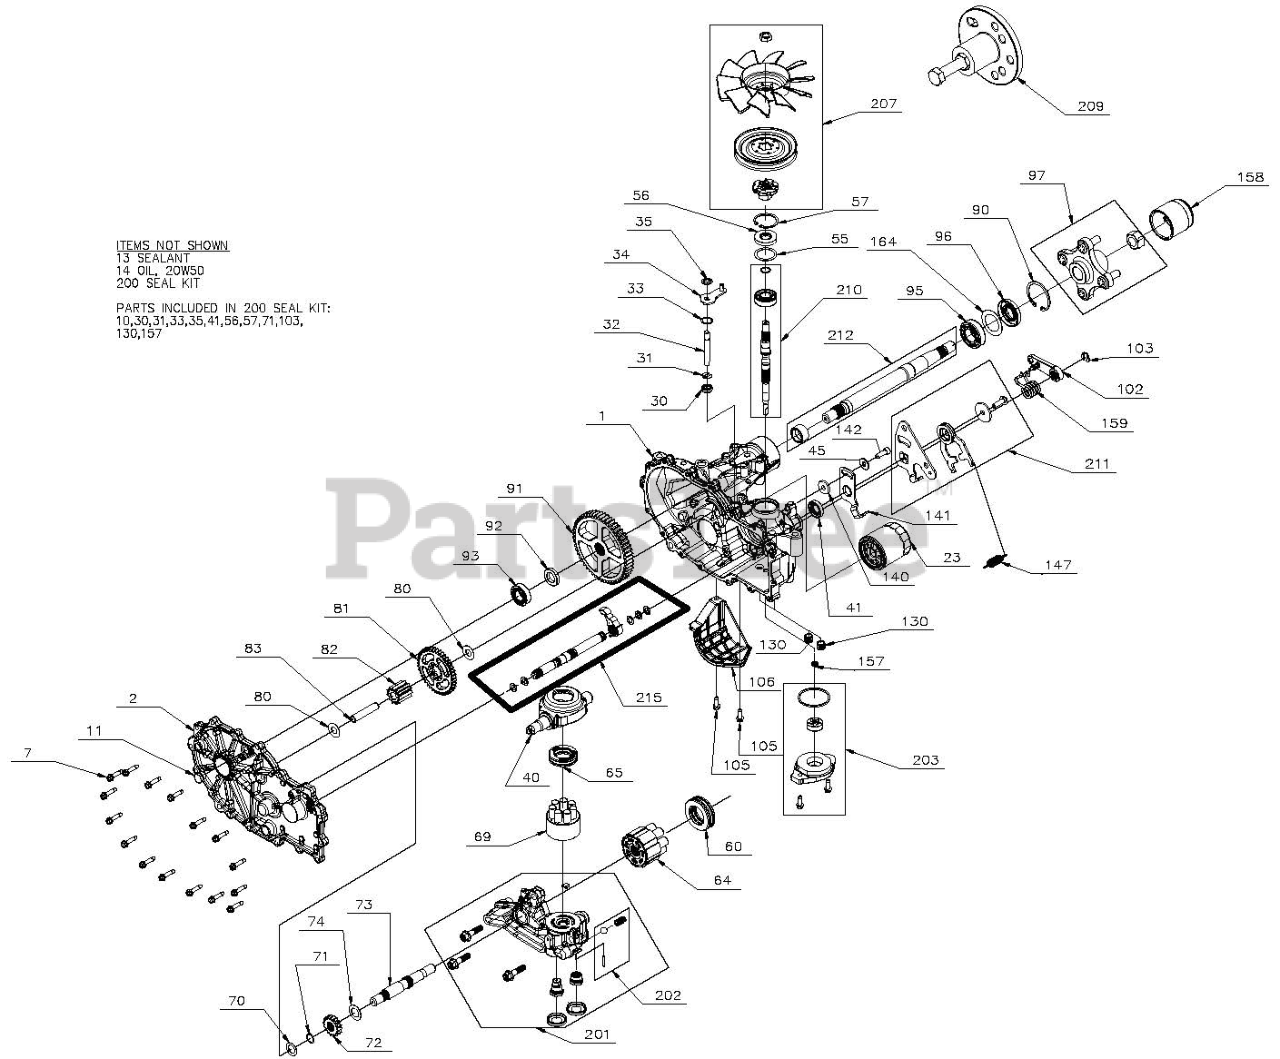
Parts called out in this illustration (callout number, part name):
7	SCREW,HEX WASHER 1/4-20X1.125
11	PLUG EXT HEX VENT 9/16 18
13	SEALANT TUBE 10.1OZ.
23	FILTER, HYDRO-GEAR 2800 TRANS
30	Seal, lip .375 x 375 x 325
31	RING. RETAINING
32	ROD, BYPASS
33	RING, RET .750
34	HG BYPASS ARM (52370)
35	RING, RTNG .
40	TRUNNION, SWASHPLATE
55	WASHER 1.23X1.56X.04
57	RING, RET 1.56 INT
60	HG THRUST BEARING (51462)
64	HG 16CC CYLINDER BLOCK (71579)
65	BEARING. THRUST 30 X 52 X 13
69	ASSY, BLOCK 7 PISTON
71	RING, RET 62 EXT
72	GEAR, 16T (STEEL)
73	SHAFT, MOTOR
74	WASHER .71 X 1.16 X .04
80	WASHER .5X1.0X.032
82	GEAR 11 TOOTH STEEL
83	JACK SHAFT (PIN)
90	RING, RETAINING
91	GEAR 54 TOOTH
92	SPACER
93	KIT, BEARING
95	BEARING, BALL 25.4 X 52 X 15
96	SEAL, LIP
97	KIT, HUB 4 BOLT
102	HG ACTUATING KIT HANDLE
103	CLIP,BRAKE ARM HYDROGEAR 52027
106	HG FILTER GUARD LH (52247)
130	TUBE CHARGE TRIPLE ORING
141	ARM, NEUTRAL LEFT
142	SHCS 5/16-24X1 PATCH
147	SPRING, HYDROGEAR P/N 51833
157	KIT GEROTOR SEAL
158	CAP, AXLE
159	SPRING, TORSION, CW
164	WASHER, 1.355 x 2.035 x .021 FLAT
200	KIT, SEAL
201	KIT, CENTER SECTION, LH CHARGE
202	KIT CHARGE RELIEF
203	KIT, CHARGE
207	KIT, FAN / PULLEY
209	HUB PULLER 5 BLT
210	INPUT SHAFT 2800 HYDGEAR 71442
211	RING, RTNG .
212	KIT SHAFT AXLE
